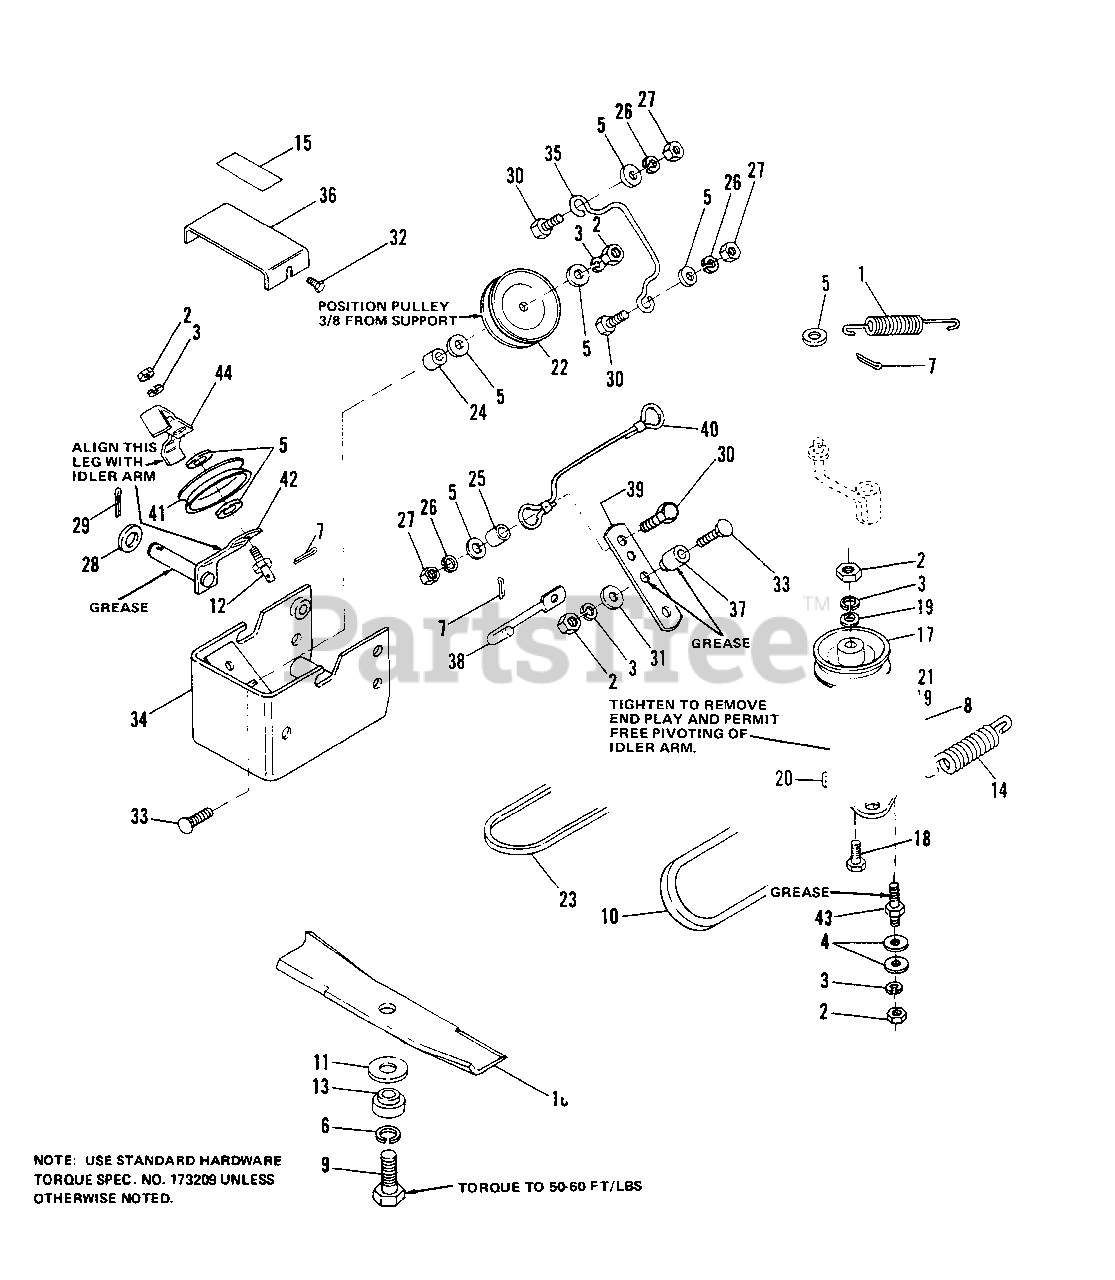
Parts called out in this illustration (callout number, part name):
2	NUT, Hex, 3/8-16
3	LOCKWASHER, Spring, 3/8
4	WASHER, Plain, 3/8
5	WASHER, Plain, 5/16
6	LOCKWASHER, Spring, 7/16
7	PIN, Cotter, 3/32 x 3/4
8	NUT, Hex, Full Lock, 3/8-16
9	CAPSCREW, Hex Hd., 7/16-20
10	V-BELT, Arbor Drive
11	WASHER, Belleville
13	WASHER, Shoulder
15	DECAL, Caution
16	BLADE, 42" Mower
17	PULLEY, Idler
18	CAPSCREW, Hex Hd., 3/8-16 x 1-3/4
19	WASHER, Plain, 3/8
20	LEVER ASSY, Idler
23	V-BELT
26	LOCKWASHER, Spring, 5/16
27	NUT, Hex, 5/16-18
28	WASHER, Plain, 7/16
29	PIN, Cotter, 3/32 x 1
30	CAPSCREW, Hex Hd., 5/16-18 x 1
31	WASHER, Plain, 3/8
32	SCREW, Hex Hd., Taptite, 1/4-20 x 3/8
33	BOLT, Carriage, 3/8-16 x 1-1/2
34	SUPPORT ASSY, Mower
35	STOP, Belt
36	COVER, Pulley
38	ROD, Clutch
39	BELLCRANK
40	CABLE ASSY, Brake
41	PULLEY, Idler
42	LEVER ASSY, Idler
44	GUIDE ASSY, Belt
